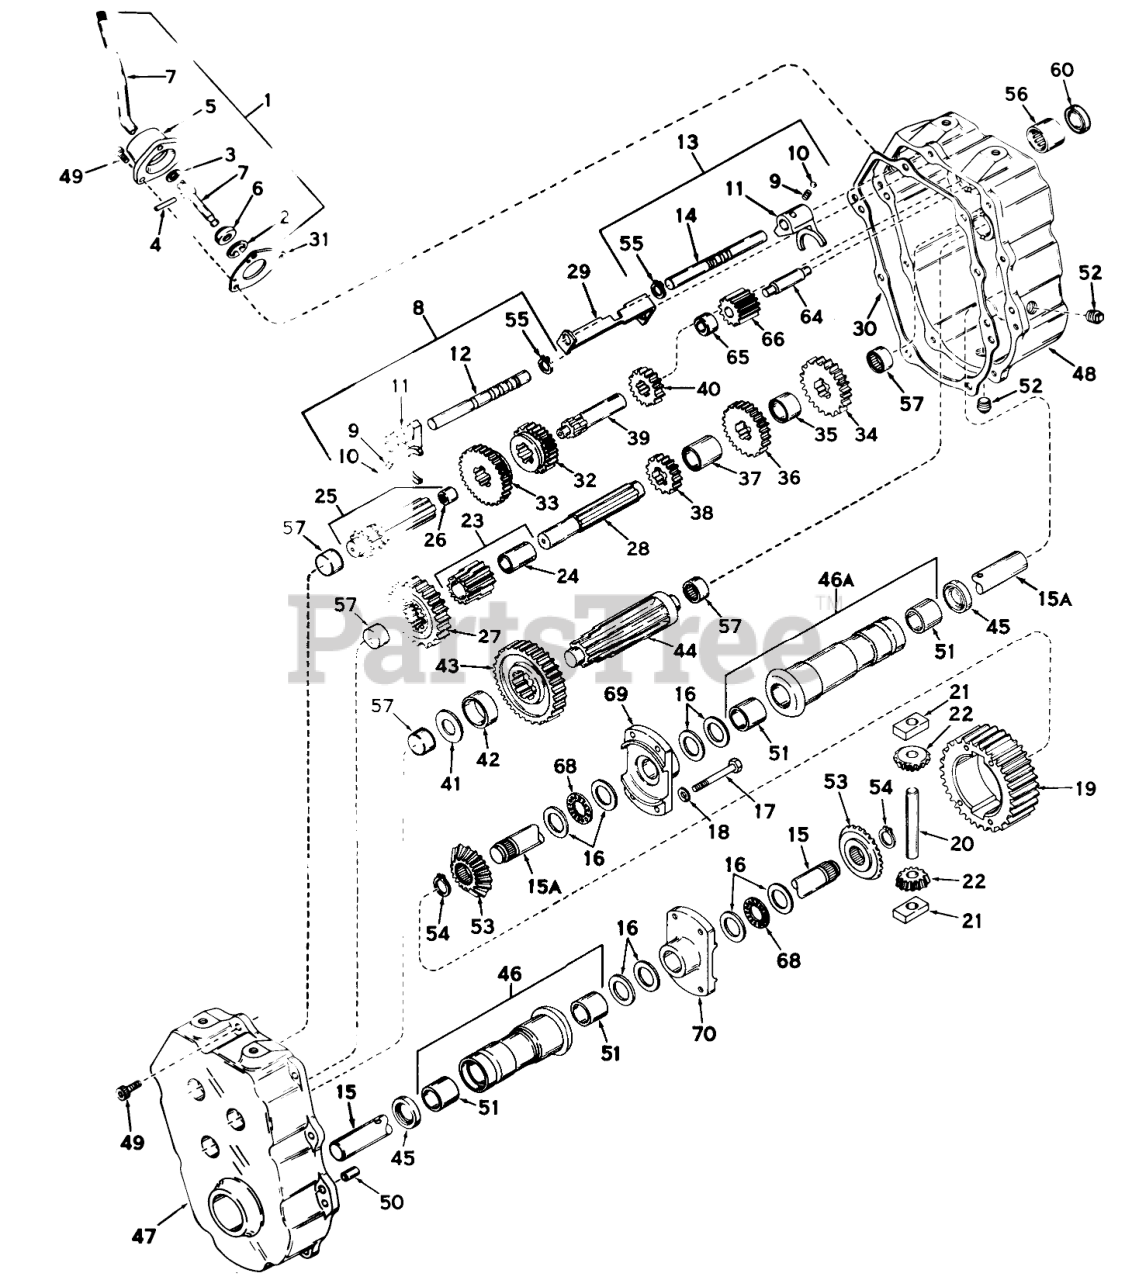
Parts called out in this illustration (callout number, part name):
1	Lever Housing Assy., Shift (Incl. Nos. 2 thru 7)
2	Ring-Snap
3	O Ring
4	Roll Pin
5	Shift Lever Housing
6	Keeper-Shift Lever
7	Lever, Shift
8	Rod Assy., Shift (Incl. Nos. 9, 10, 11, 14 24)
9	Spring
10	Piston ASM
11	Shift Fork
12	Rod, Shifter
13	Rod Assy., Shift (Incl. Nos. 9 thru 12 24)
14	Rod, Shifter
15	Axle, L.H.
15A	Axle, R.H.
16	Washer
17	Screw-Hex Hd.
18	Lockwasher
19	Gear, Ring
20	Pin-Drive
21	Biock-Drive
22	Pinion-Bevel
23	Pinion Bushing Assy. (Incl. No. 24)
24	Bushing
25	Shaft Bearing Assy., Shifter (Incl. No. 26)
26	Bearing
27	Gear-Spur
28	Shaft, Idler
29	Stop-Shifter
30	Gasket, Case to Cover
31	Shift Lever Housing Gasket
32	Gear, Shifting
33	Gear, Shifting
34	Gear, Spur (26 teeth)
35	Spacer
36	Gear, Spur (22 teeth)
37	Spacer
38	Gear, Spur (16 teeth)
39	Shaft, Input
40	Gear (10 teeth)
41	Washer
42	Spacer
43	Gear-Output
44	Shaft, Output
45	Seal, Oil
46	Housing Bushing Assy., L.H. Axle (Incl. Nos. 51)
46A	Housing Bushing Assy., R.H. Axle (Incl. No. 51)
47	Cover Assy., Transaxle (Incl. No. 57)
48	Case Assy., Transaxle (Incl. Nos. 56 57)
49	Screw
50	Dowel Pin
51	Bushing
53	Gear-Bevel
54	Ring-Snap
55	Ring-Snap
56	Bearing
57	Bearing
60	Oil Seal
64	Shaft, Reverse idler
65	Spacer, Reverse idler
66	Idler Reverse
68	Bearing-Thrust
69	Carrier, Differential
70	Carrier, Differential
